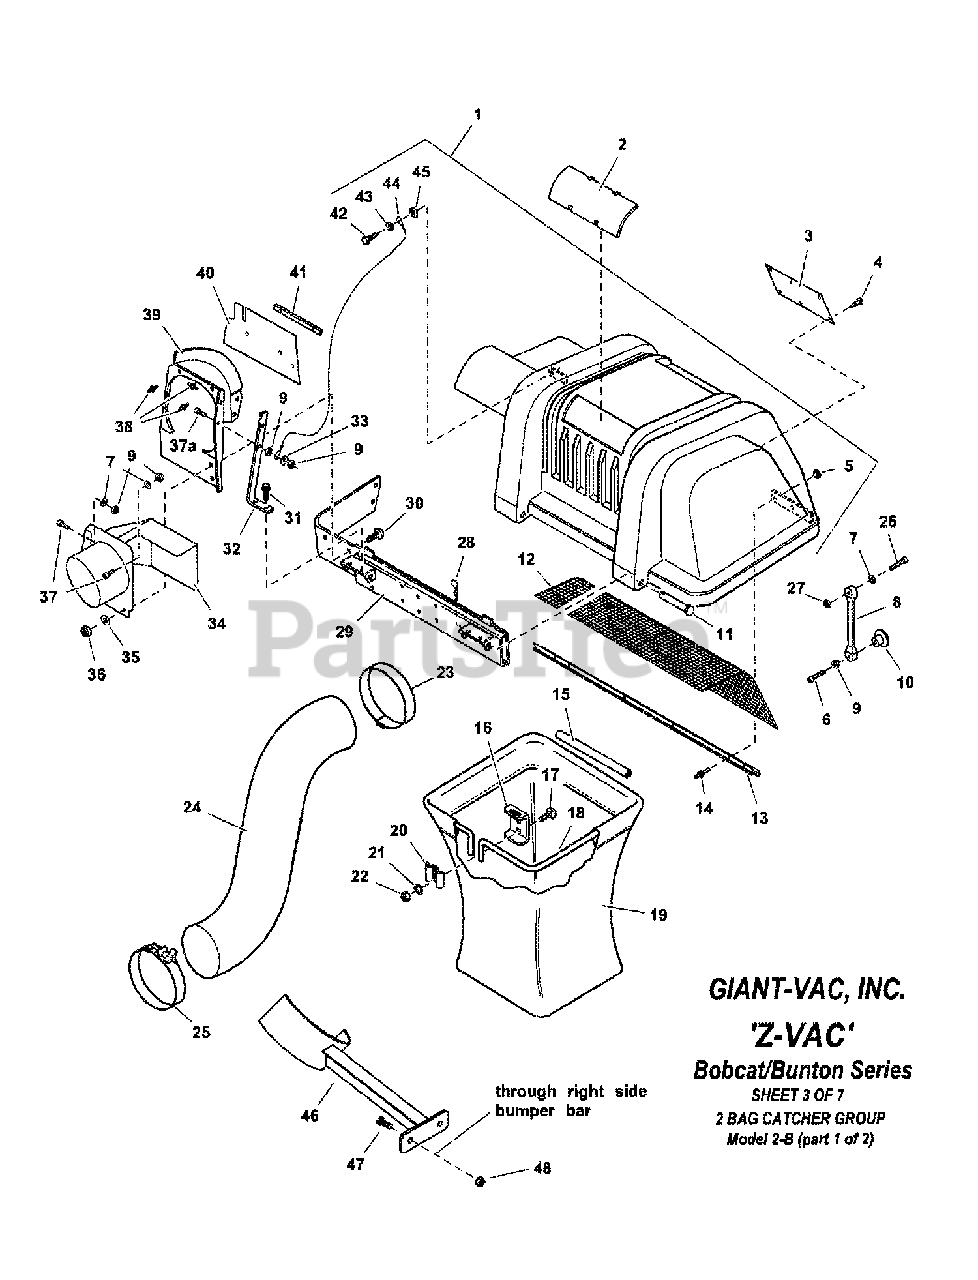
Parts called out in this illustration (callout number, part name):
1	ASSEMBLY, 2 Bag Cover and Screen
2	WINDOW, Cover
3	* DECAL, Safety, Grass Bag
4	CLIP, Canoe
5	WASHER, .188 Rivet
6	SCREW, #10-32 x 1-1/2 Hex Washer Head Machine w/Nylon Patch
7	WASHER, .19 x .38 x .06 Flat
8	STRAP, Rubber
9	NUT, #10-32 Hex Nyloc
11	PIN, Round Head
12	SCREEN
13	SEAL, Clip
14	POP RIVET, 3/16 x .265 Alum.
15	TUBE CLIP, Grass Bag
16	HANGER, Grass Bag
17	BOLT, 5/16-18 x 3/4" Square Neck Carriage, GR5
18	HOOP, Grass Bag
19	GRASS BAG
20	CLAMP, Grass Bag
21	WASHER, 5/16" Split Lock
22	NUT, 5/16-18 Hex, GR5 or B
23	HOSE CLAMP, Upper
24	HOSE, Snapper Fast Vac
25	HOSE CLAMP, Lower, Fast Vac
26	SCREW, #10-24 x 1-1/4" Hex Head Cap, GR5
27	NUT, #10-24 Hex Nyloc
28	HAIR PIN, 2.62 Cotter
29	CROSS ASSEMBLY
30	BOLT, 1/4-20 x 3/4" Short Neck Carriage
31	SCREW, 1/4-20 x 3/8" Hex Washer Self-Tap
32	STRAP, Tube Support
33	WASHER, .191 I.D. Flat
34	WELDMENT, Hose Adapter/Deflector
35	WASHER, 1/4" Flat
36	NUT, 1/4-20 Hex Nyloc
37	SCREW, 10F x 7/8" Pan Head Cross Recess
38	POP RIVET, 3/16"
39	SUPPORT, Tube
40	SEAL, 2 Bag Catcher
41	BRACKET, Seal
42	SCREW, #10-12 x 5/8" Hex Washer Self-Tap
43	WASHER, 1/4" Split Lock
44	CABLE, Double Loop
45	NUT, Speed
46	WELDMENT, 2 Bag Hose Support
47	SCREW, 5/16-18 x 3/4" Hex Head Cap, GR5
48	NUT, 5/16-18 Hex Flange Lock
